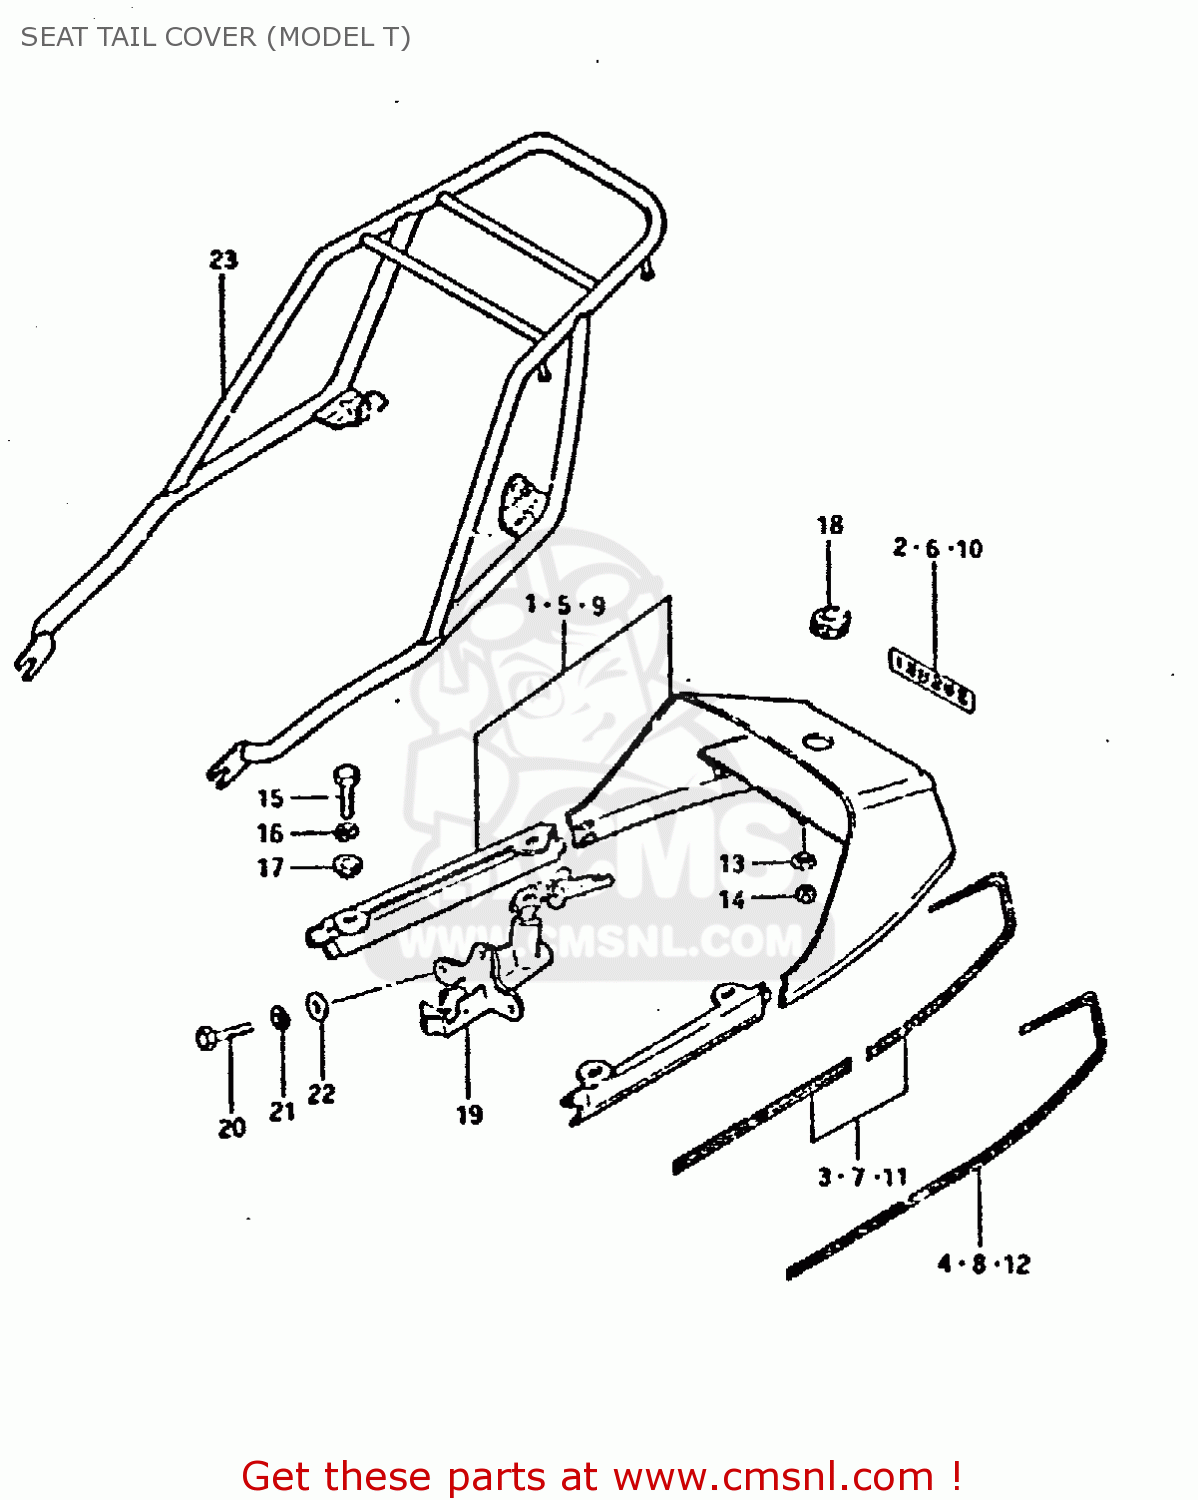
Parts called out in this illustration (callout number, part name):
1	COVER SET, SEAT TAIL (BLACK)
2	EMBLEM (GOLD/BLACK)
3	TAPE SET
4	TAPE SET
5	COVER SET, SEAT TAIL (RED)
6	EMBLEM (GOLD/BLACK)
7	TAPE SET
8	TAPE SET
9	COVER SET, SEAT TAIL (BLUE)
10	EMBLEM (GOLD/BLACK)
11	TAPE SET
12	TAPE SET
13	WASHER
14	NUT 6MM
15	BOLT
16	LOCK WASHER
17	WASHER
18	GROMMET,SEAT LOCK HOLE
19	LOCK SET
20	BOLT
21	LOCK WASHER
22	WASHER 6MM
23	CARRIER
